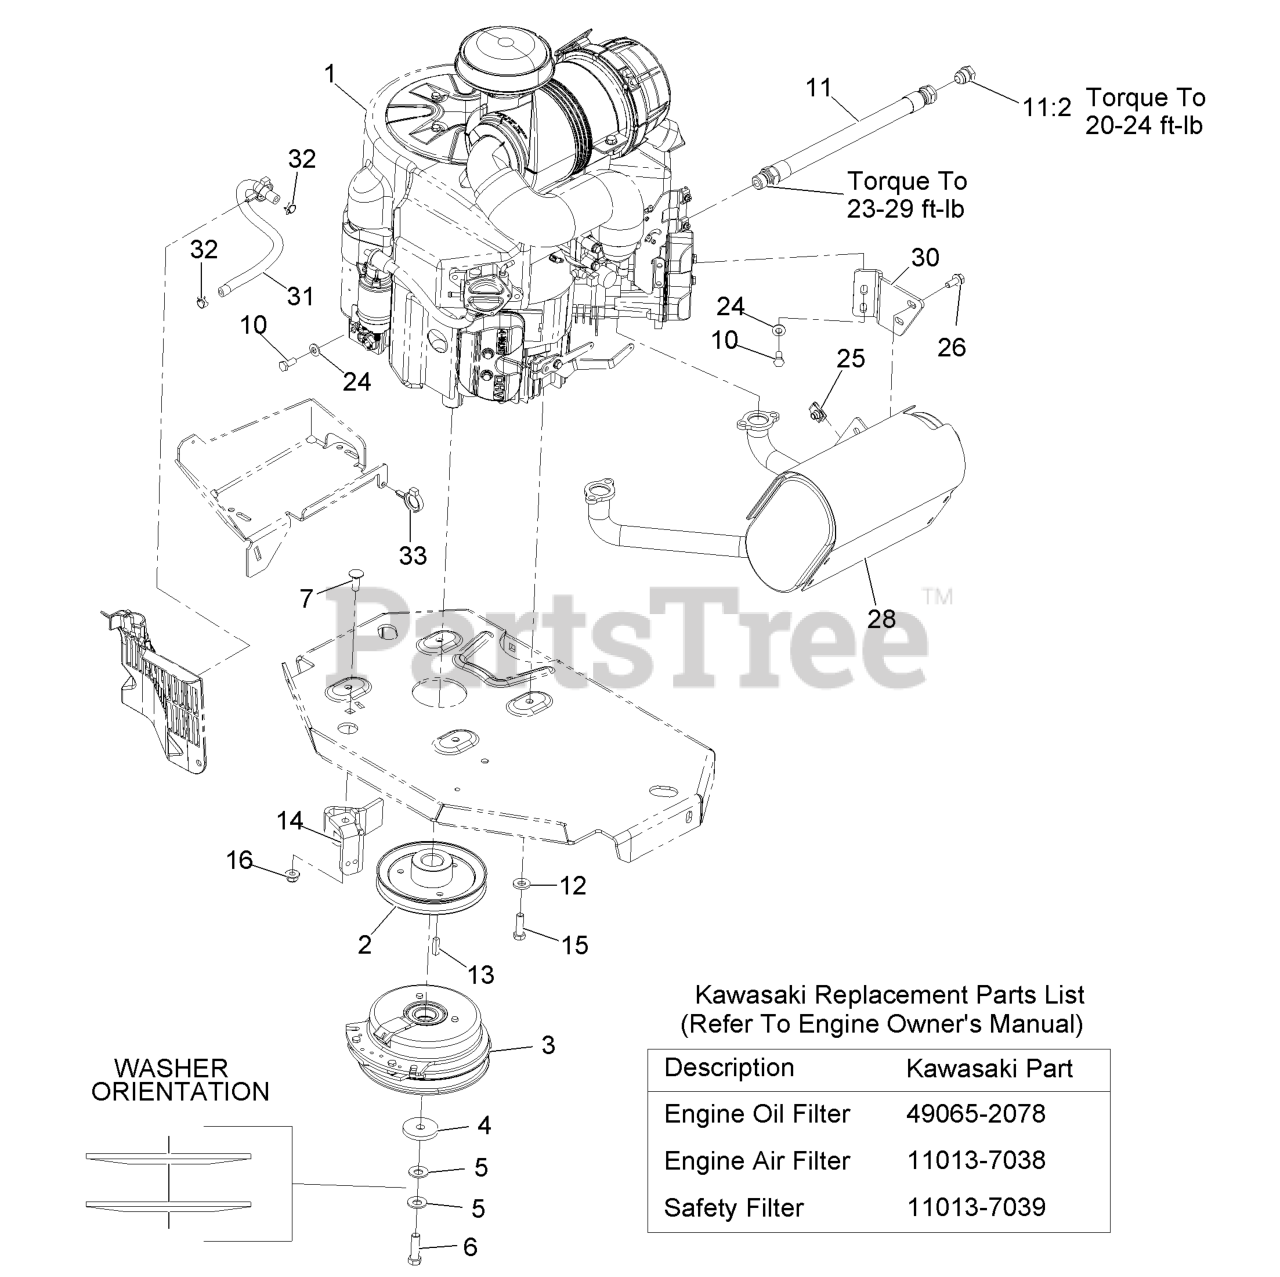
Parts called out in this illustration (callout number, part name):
2	SHEAVE
3	CLUTCH KIT
4	WASHER-CLUTCH
5	WASHER-SPRING
6	SCREW-HH 7/16-20 X 1 1/2 W/LOCTITE
7	SCREW-CARR
10	SCREW-HH
12	WASHER-BELLEVILLE
14	CLUTCH-ANCHOR
15	SCREW-HH
16	NUT-HF, NI
24	WASHER-SPRING
26	SCREW-HHF
28	MUFFLER
30	BRACKET-MUFFLER
31	HOSE-FUEL
32	CLAMP-HOSE
33	CLAMP-HOSE
